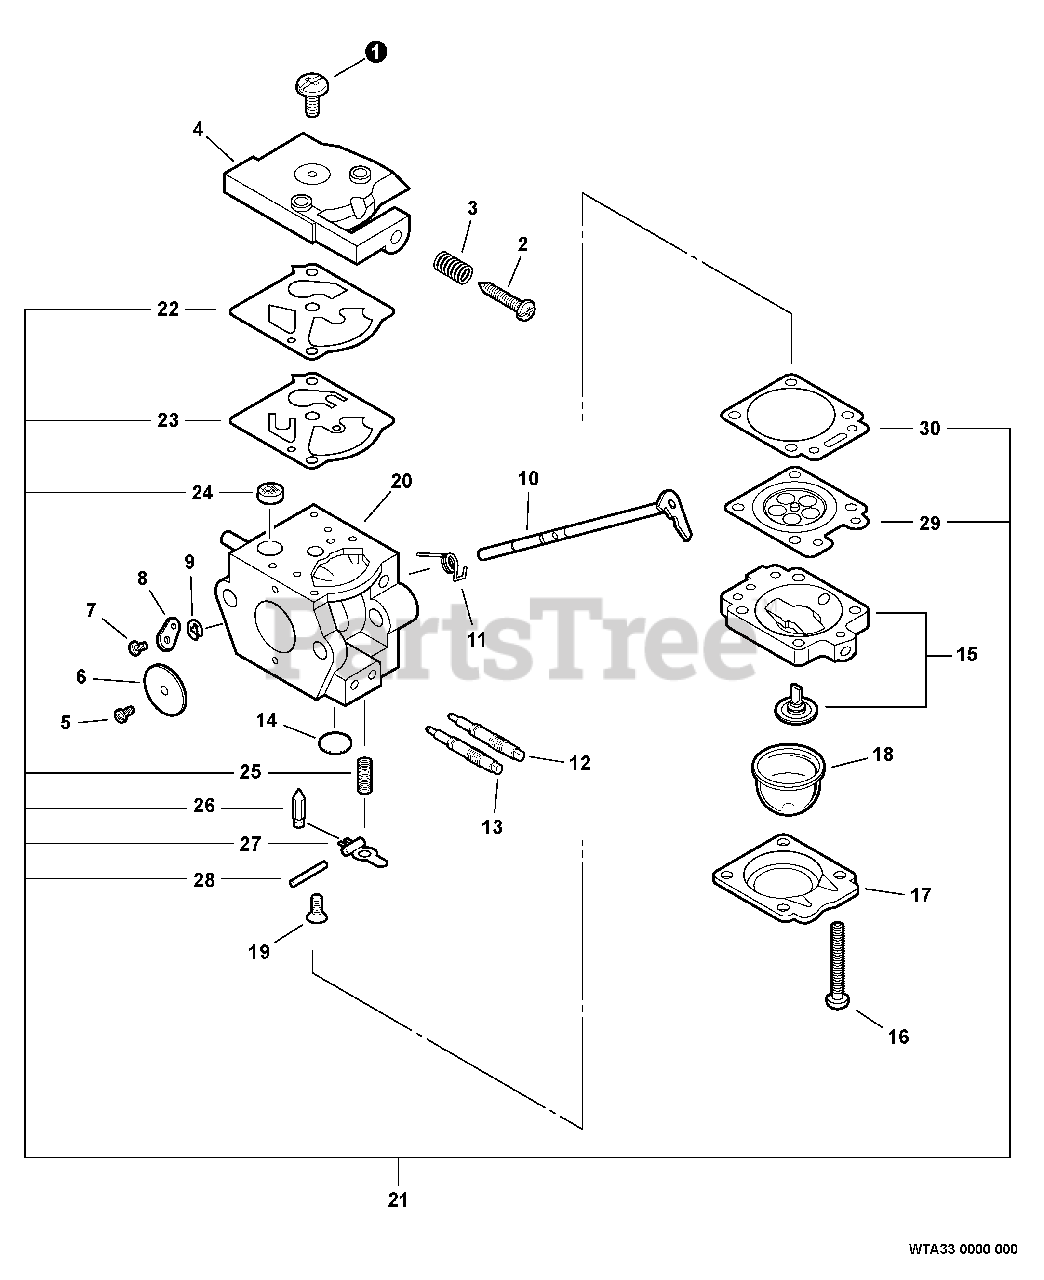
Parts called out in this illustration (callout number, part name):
1	SCREW, PUMP COVER
2	SCREW, IDLE ADJUST
3	SPRING, IDLE ADJUST
4	COVER, PUMP
6	VALVE, THROTTLE
8	THROTTLE, LEVER
9	RING, RETAINING
10	SHAFT, THROTTLE
12	NEEDLE - LOW SPEED
13	NEEDLE - HIGH SPEED
14	PLUG, WELCH
15	BASE, PURGE
17	RETAINER, PURGE BULB
18	BULB, PURGE
19	SCREW, METERING LEVER PIN
20	BODY, CARBURETOR
21	REPAIR KIT
22	GASKET, PUMP
23	DIAPHRAGM, PUMP
24	STRAINER
26	VALVE, INLET NEEDLE
27	LEVER, METERING
28	PIN, METERING LEVER
29	DIAPHRAGM, METERING
30	GASKET, METERING
